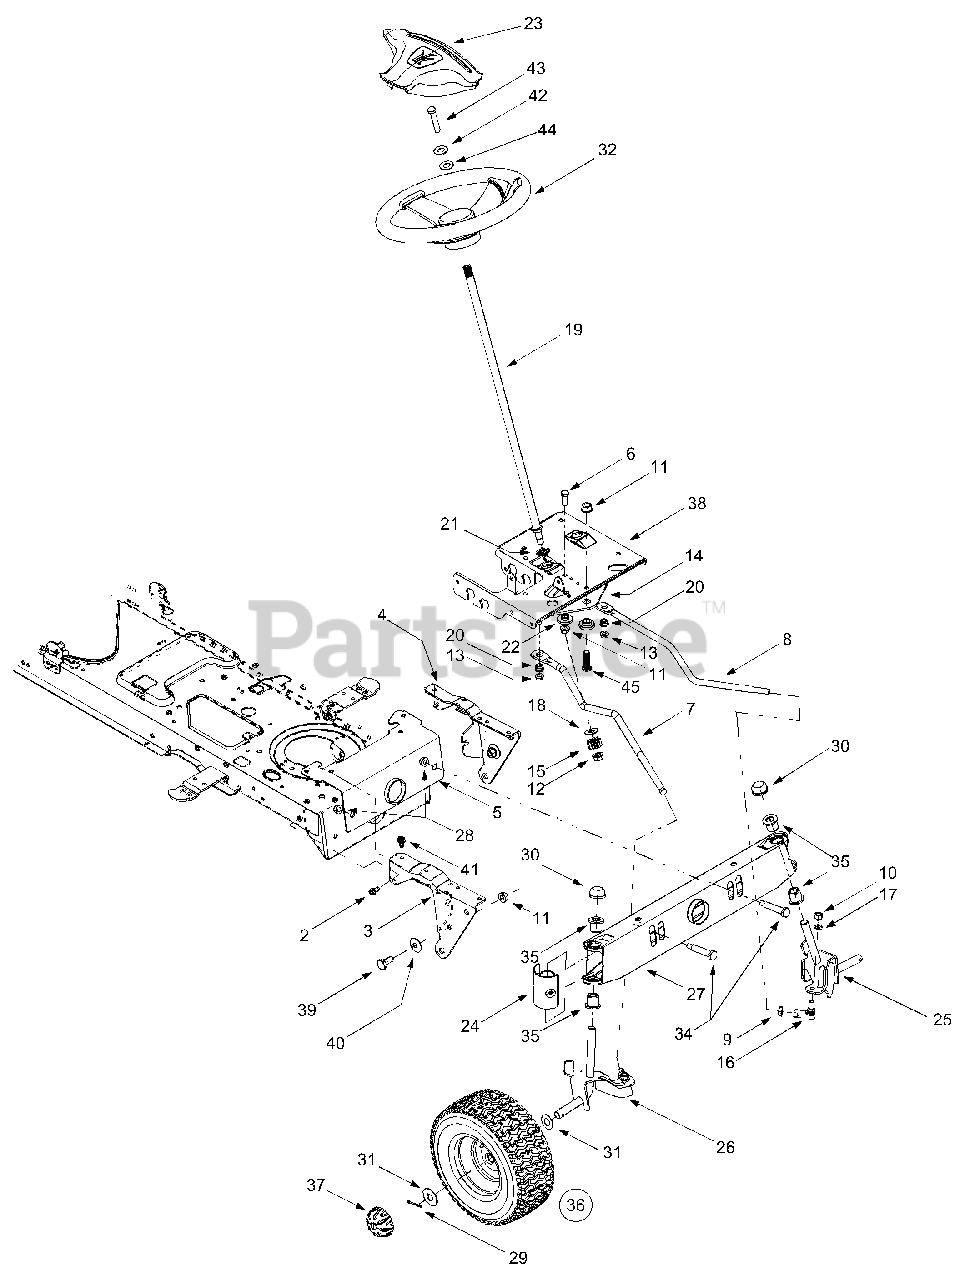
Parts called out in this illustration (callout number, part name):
2	Self-tapping Screw, 5/16-18 x.875
6	Hex Cap Screw, 3/8-16 x 1.00 (Grade 5)
7	RH Drag Link
8	LH Drag Link
9	Jam Nut, 7/16-20 (Grade 2)
10	Hex Nut, 3/8-24 (Grade 2)
11	Flange Lock Nut, 3/8-16
12	Flange Lock Nut, 7/16-20
13	Flange Lock Nut, 5/16-18
14	Steering Gear, 11/90 Ratio
15	Steering Pinion Gear
16	Ball Joint, 7/16-20
17	Lock Washer, 3/8
18	Flat Washer,.51 x 1.12 x.06
19	Steering Shaft,.625 OD x 24.4
20	Plastic Bushing,.38 ID
21	Hex Flange Bearing, 5/8
22	Shoulder Spacer,.38 ID
23	Steering Wheel Cover
24	Pivot Bar End Cap w/ Fitting
25	LH Axle Assembly,.75 Diameter
26	RH Axle Assembly,.75 Diameter
28	Flange Lock Nut, 3/8-16
29	Cotter Pin
30	Push Cap,.75
31	Flat Washer,.78 x 1.589 x.06
32	Steering Wheel, Soft Grip, Three Spoke
34	Shoulder Screw,.5 x 2.2, 3/8-16
35	Flange Bearing,.76 ID x.937 OD
37	Deluxe Hub Cap
39	Shoulder Screw, 3/8-16
40	Bell Washer,.39 x 1.13 x.062
41	Self-tapping Screw, 5/16-18 x.75
42	Bell Washer,.34 x.872
43	Hex Bolt, 5/16-18 X 1
44	Flat Washer,.406ID x.875OD
45	Hex Cap Screw, 3/8-16 x 1.00
